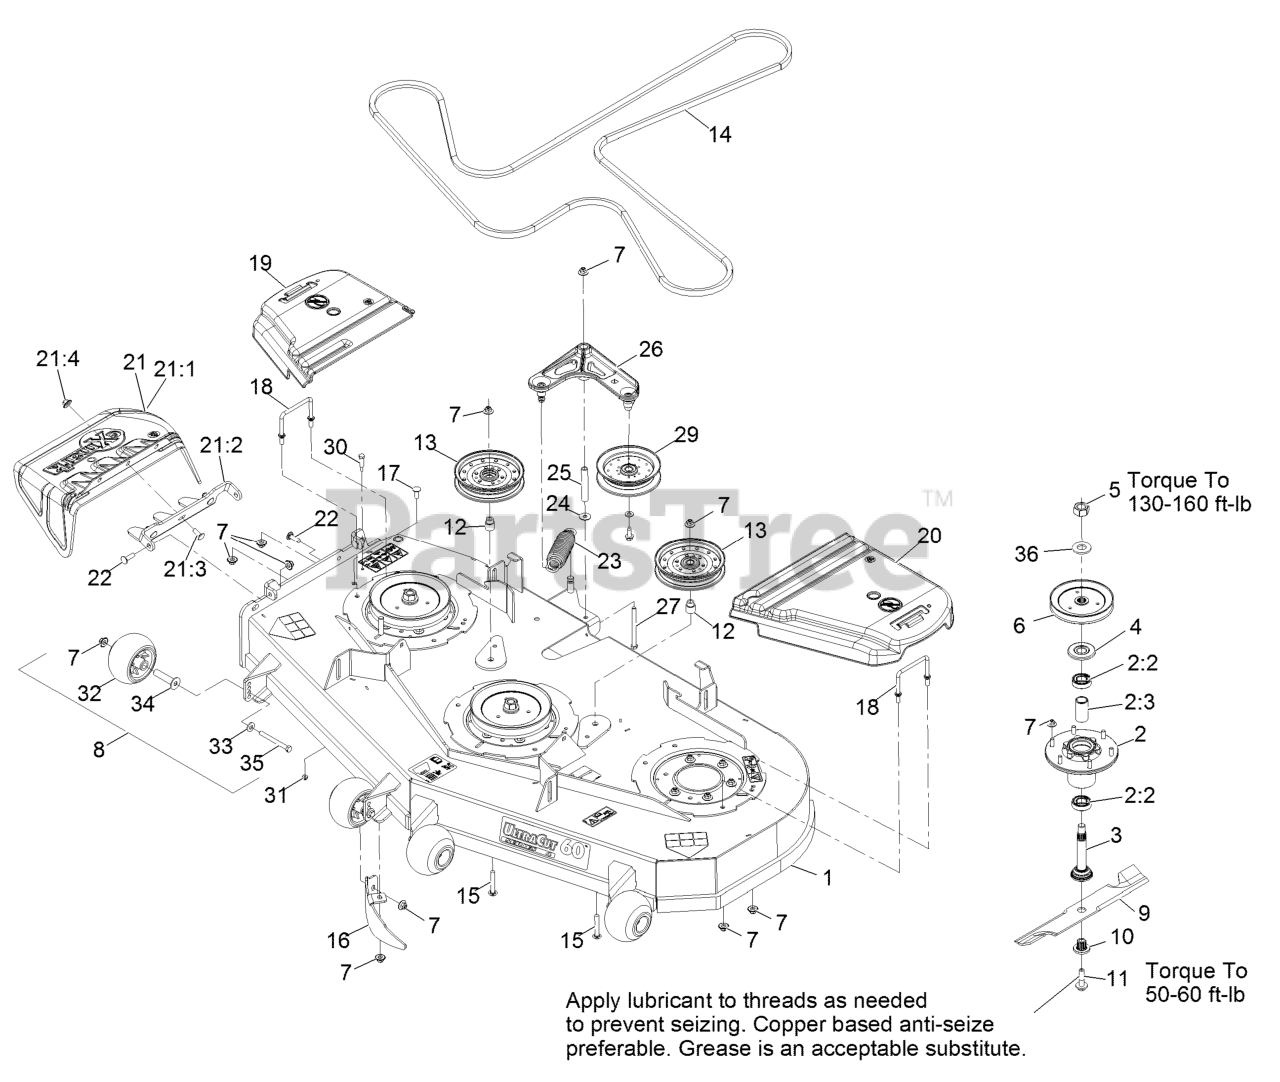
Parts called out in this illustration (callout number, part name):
1	DECK ASM,W/DECALS 604
2	ASM-CUTTER HSG WITH BEARINGS
2:2	BEARING-BALL
2:3	SPACER-BEARING
3	ASM-SPINDLE AND SEAL
4	GUARD,BEARING TOP .989
5	NUT-HEX
6	SHEAVE,BLADE DRIVE 7.25
7	Nut-Nyloc 3/8-16 Flg
8	KIT, ANTI-SCALP ROLLER
9	Blade-Extreme 2, 20.50"
10	BUSHING,SPLINED
11	SCREW,SEMS 1/2-20 X 2.19
12	BUSHING-IDLER
14	BELT-V
15	SCREW-CARR
16	DOGLEG - LZ60
17	SCREW-CARR
18	WIREFORM-COVER
19	COVER-BELT, RH
20	COVER-BELT, LH
21	ASM,DISCHARGE CHUTE
21:1	CHUTE,DISCHARGE
21:2	BRACKET,DISCHARGE CHUTE
21:3	SCREW-CARR
21:4	Nut-Nyloc 3/8-16 Flg
22	Bolt-Carriage 3/8-16 X 1 1/4
23	SPRING-EXTENSION
25	BUSHING
26	IDLER ARM ASM
27	SCREW-HH
30	BOLT-SHOULDER
32	ROLLER-SCALP, ANTI
33	WASHER-BELLEVILLE
34	AXLE, ROLLER
35	SCREW-HH 3/8-16 X 3 3/4 GR 8
